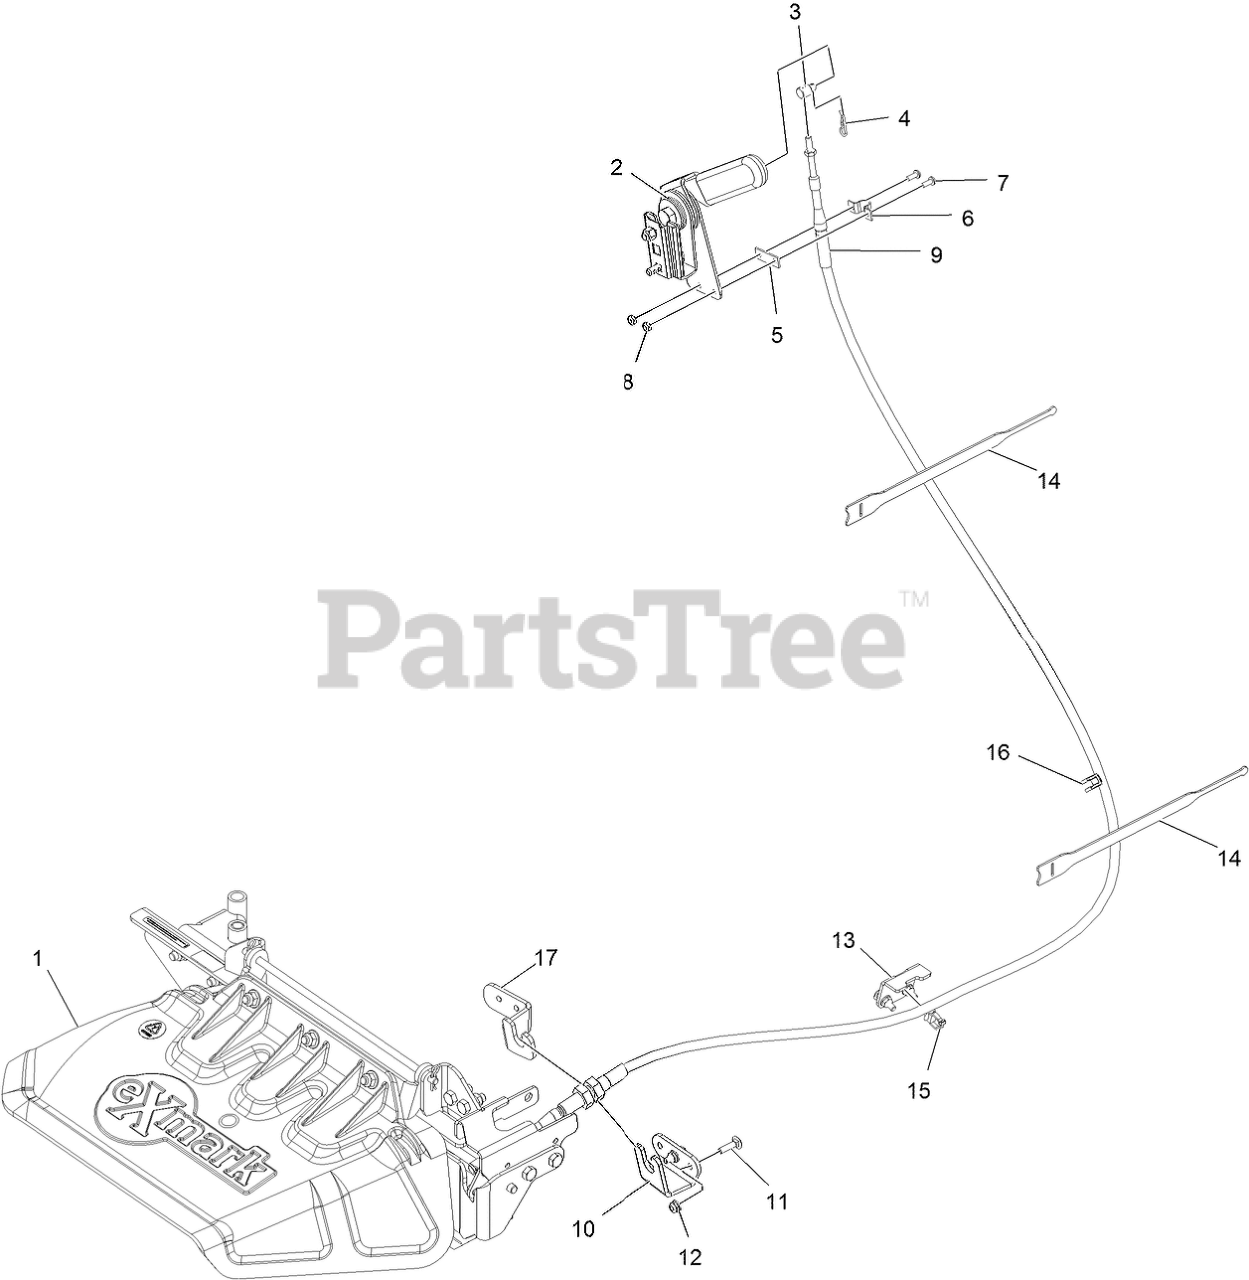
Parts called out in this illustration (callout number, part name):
1	ASM, OCD
2	ASM, HAND LEVER
3	PIVOT, CONTROL CABLE
4	PIN-COTTER
5	SHIM,CONTROL CABLE
7	SCREW-PPH
8	NUT-LOCK, NI
9	Cable,Discharge Gate
10	Plate-Discharge, Ocd
11	SCREW-CARR
13	Brkt-Cable
14	STRAP-VELCRO, CABLE TIE
15	CLIP-TIE
16	Clip-Edge
17	Brkt-Ocd Cable
